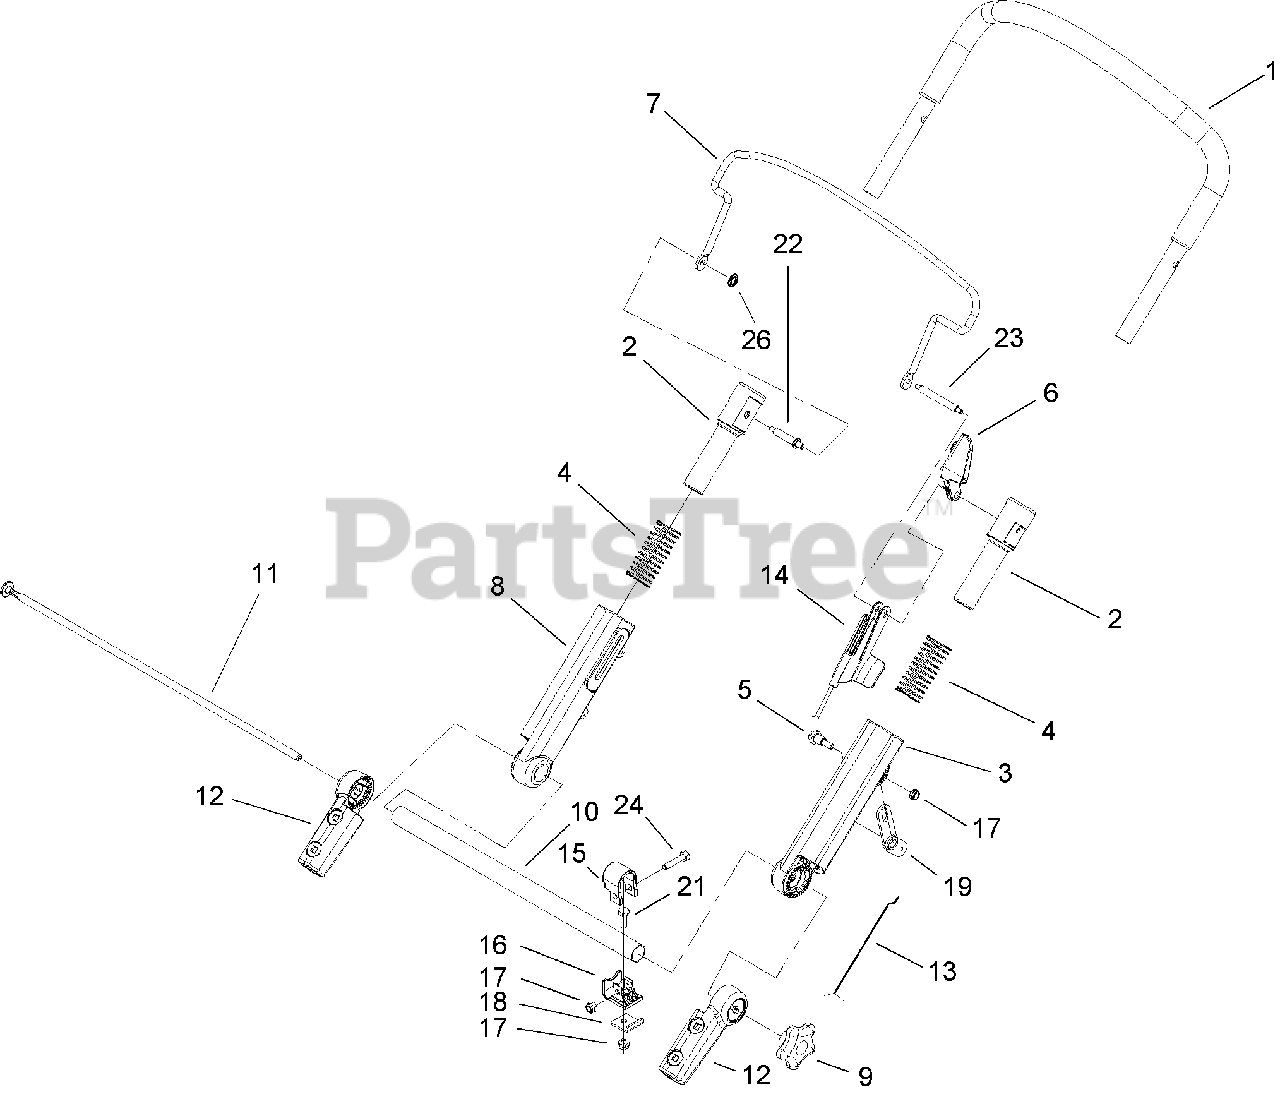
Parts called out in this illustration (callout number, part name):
1	UPPER HANDLE ASM
2	SLEEVE-HANDLE
3	SLIDE-TOP, LH
4	SPRING-COMPRESSION
5	BOLT-SHOULDER
6	STOP-BAIL
8	SLIDE-TOP, RH
11	ROD-THREADED
12	MOUNT-HANDLE, LOWER
13	CABLE-TRACTION
14	CABLE-BRAKE
15	SUPPORT-CABLE
16	SUPPORT-GUIDE, CABLE
17	NUT-LOCK, NI
18	CLAMP-CABLE
19	LEVER-TRACTION
21	SCREW-HH
22	PIN-HANDLE
23	PIN-BAIL, LH
24	SCREW-CARR
26	RETAINER-PUSH ON
